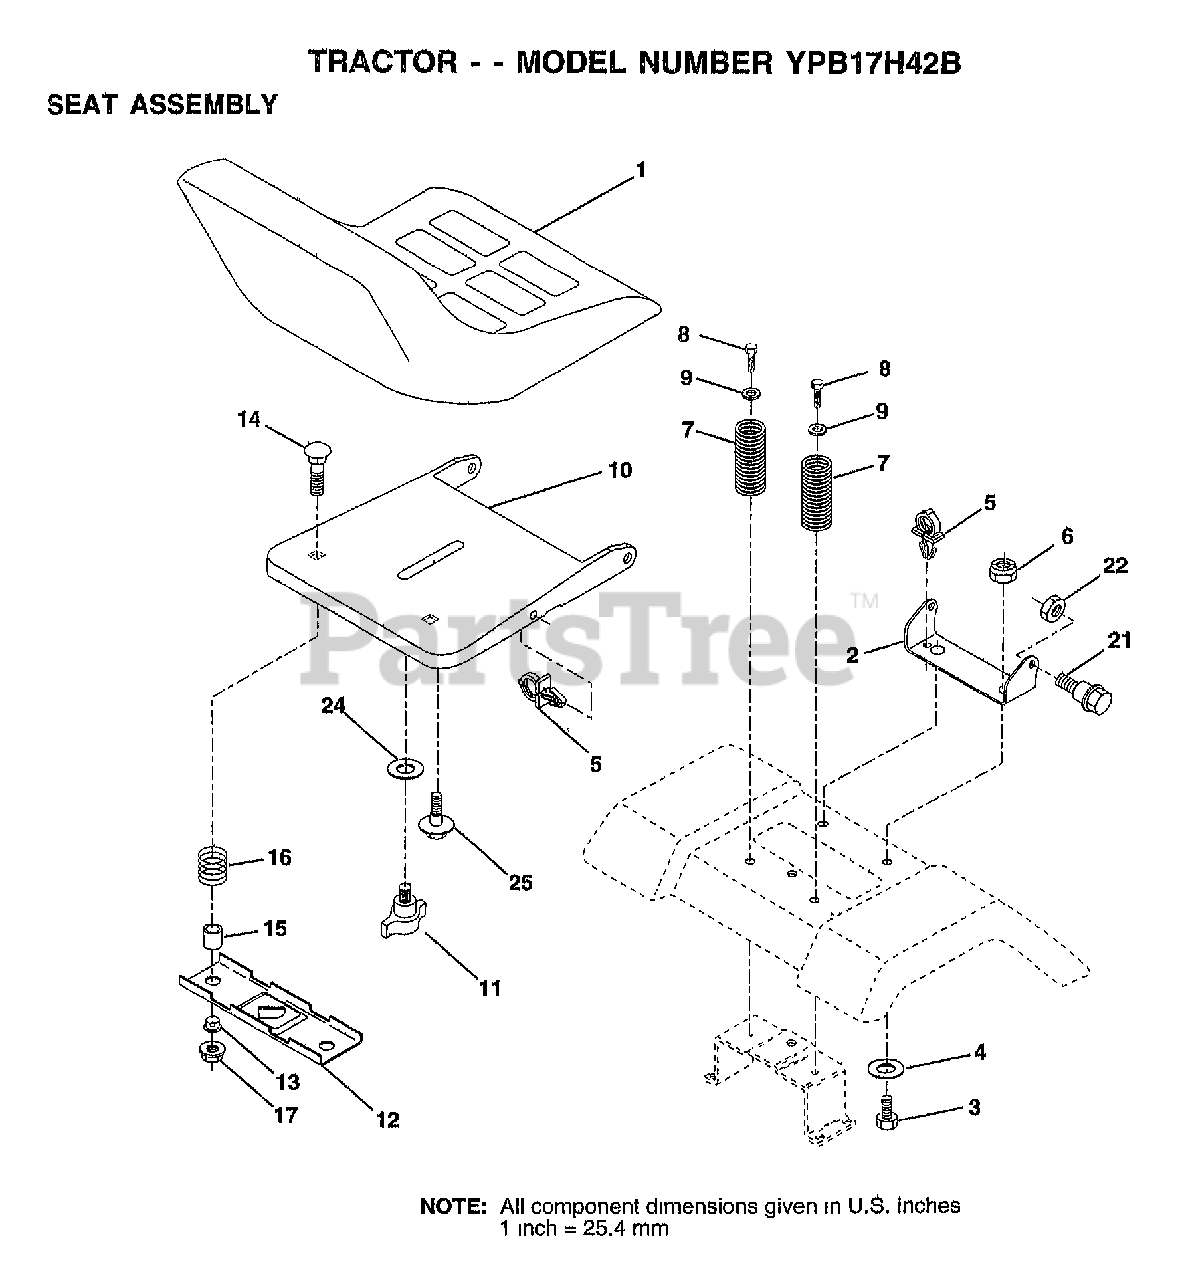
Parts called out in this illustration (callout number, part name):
1	SEAT.2400/1416.BK
2	BRACKET PVT SEAT
3	BOLT
4	WASHER PM
5	CLIP.PUSH-IN.HING
6	NUT
7	SPRING COMPRESSIO
8	SCREW
9	WASHER
10	PAN-SEAT
11	KNOB.SEAT.ADJ.WINGNUT
12	BRKT SWITCH
13	BUSHING
14	BOLT-RD HD SQ NK
15	SPLIT SPACER
16	SPRING
21	"BOLT,SHOULDER"
22	NUT
24	WASHER
25	"BOLT,SHOULDER"
